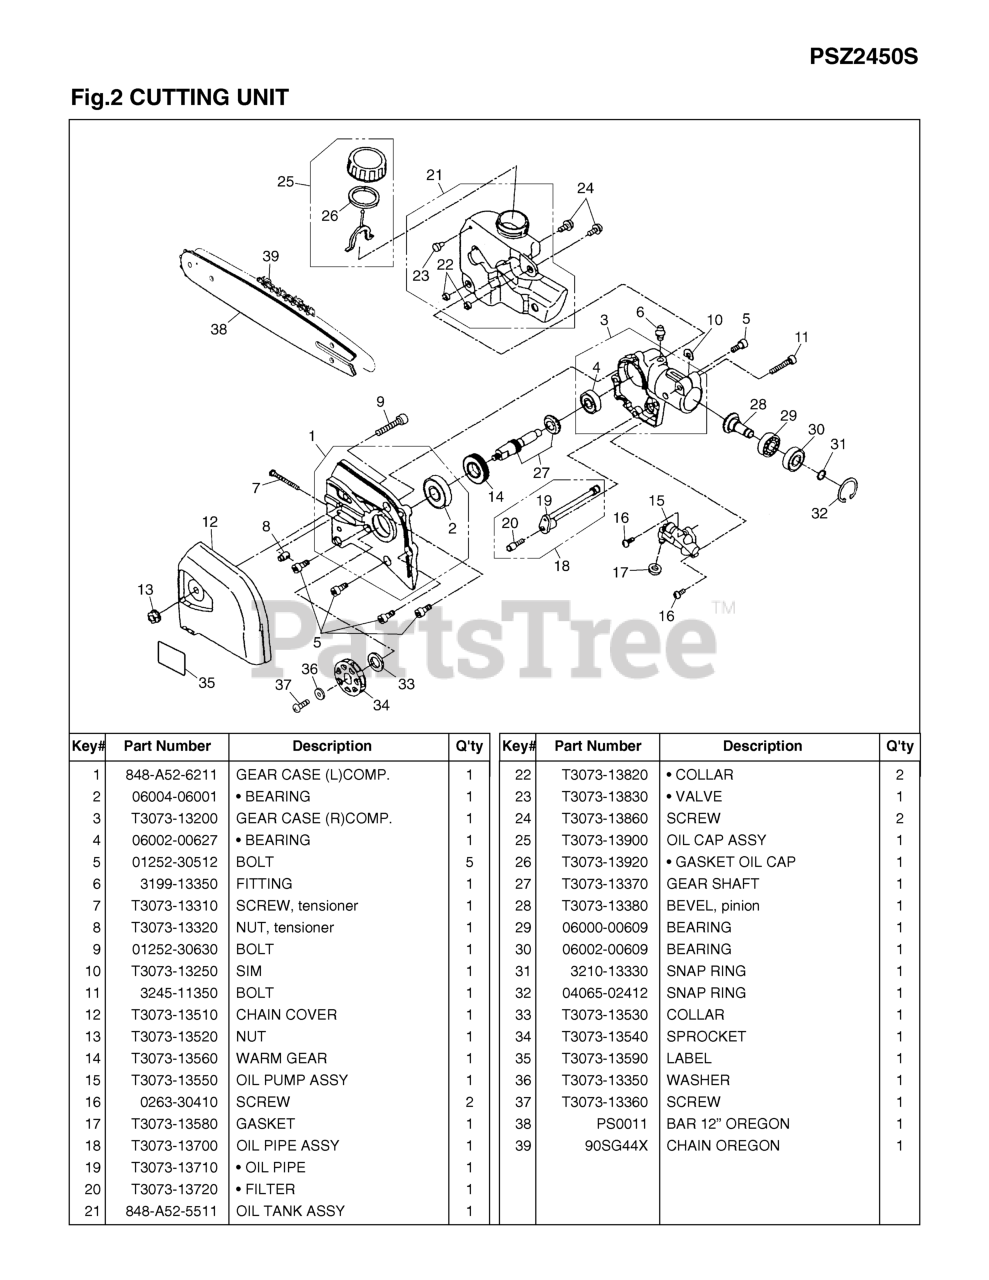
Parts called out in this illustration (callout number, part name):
1	GEAR CASE COMP-L
2	BEARING
3	GEAR CASE COMP-R
5	BOLT
6	FITTING, GREASE
7	SCREW
8	NUT
9	BOLT
10	SHIM
12	CHAIN COVER
13	NUT
14	GEAR, WORM
15	OIL PUMP ASSY
17	GASKET
18	OIL PIPE ASSY
19	OIL PIPE
20	FILTER
21	OIL TANK ASSY
22	COLLAR
23	VALVE
24	SCREW
25	CAP ASSY, OIL
26	GASKET, OIL CAP
27	GEAR SHAFT
28	BEVEL, PINION
29	BEARING
31	SNAP RING
32	SNAP RING
33	COLLAR
34	SPROCKET
35	LABEL
36	WASHER
37	SCREW
38	12
39	12
